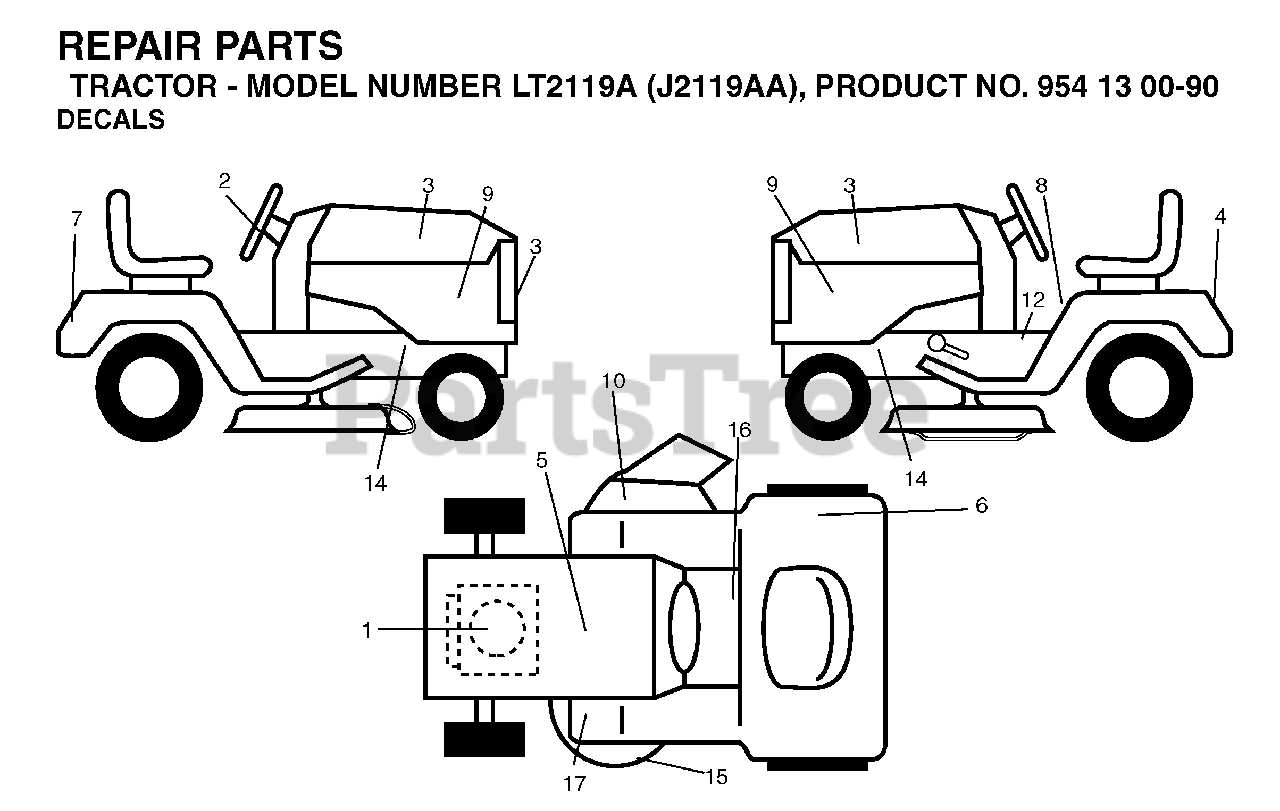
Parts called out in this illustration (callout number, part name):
5	DECAL BTRY SYMBOLS
6	DECAL.FENDER
8	DECAL READ OWNER'S MAN SYMS
10	DECAL.INTERNATIONL.CUTFINGER
12	DECAL PARK BRAKE
15	DECAL V-BELT SCHEMATIC
